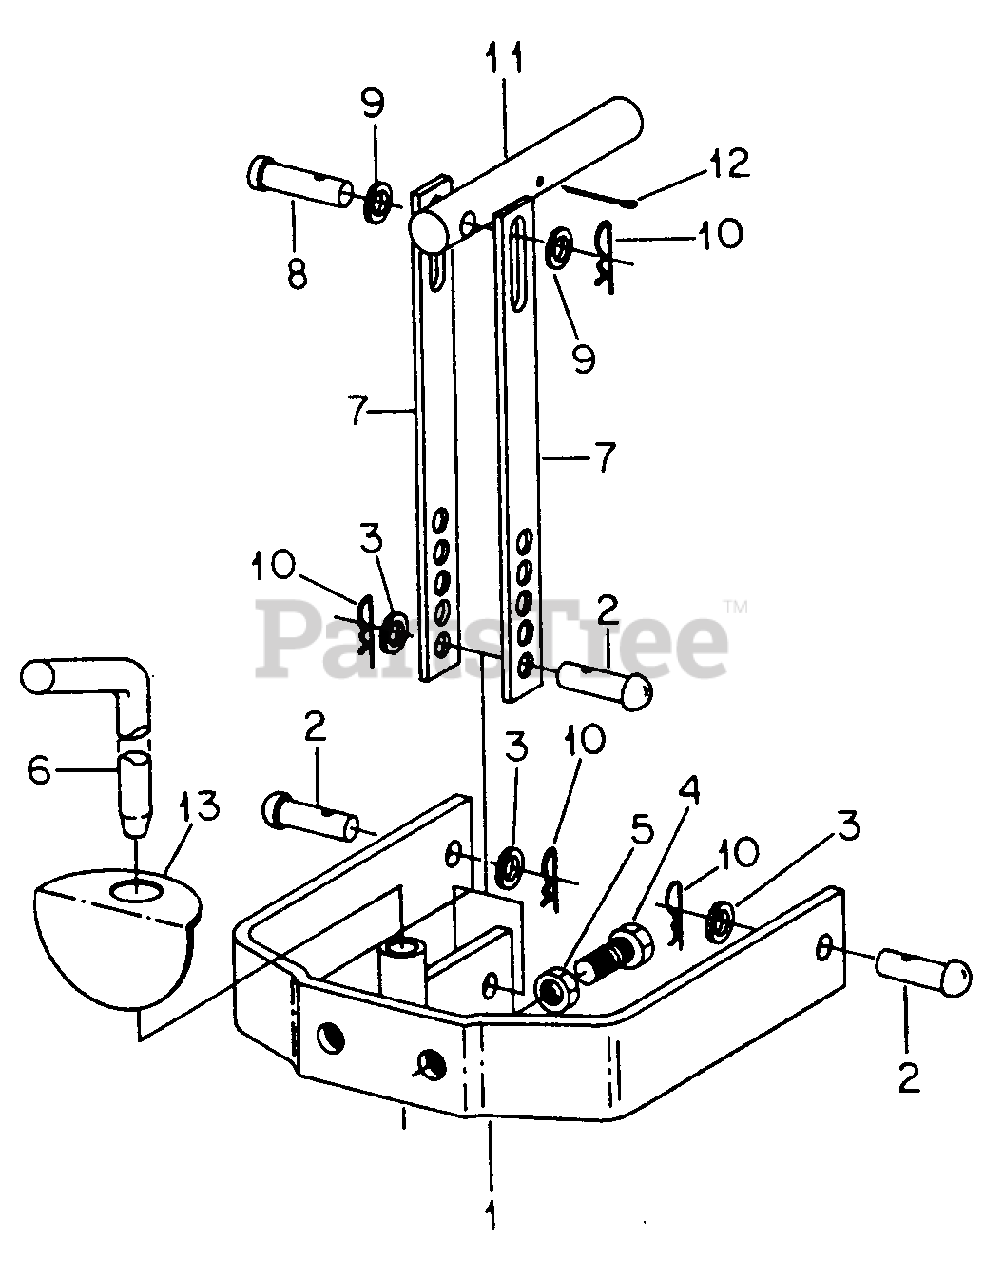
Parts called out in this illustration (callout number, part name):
1	Adapter, Sleeve Hitch
2	Pin, 1/2 X 1.500 Hd Type 1
3	Washer, .531 X 1.062 X .074
4	Bolt, 5/8 X 2 Type 5
5	Nut, 5/8 Jam Type 5
6	Pin, Sleeve
7	Strap, Lift
8	Pin, 1/2 X 2.500 Type 5 Hd
9	Washer, .531 X 1.062 X .074
10	Pin, QA Cotter
11	Rod, Lift
12	Pin, 3/16 X 2 Cot
13	Plate, Stabilizer
